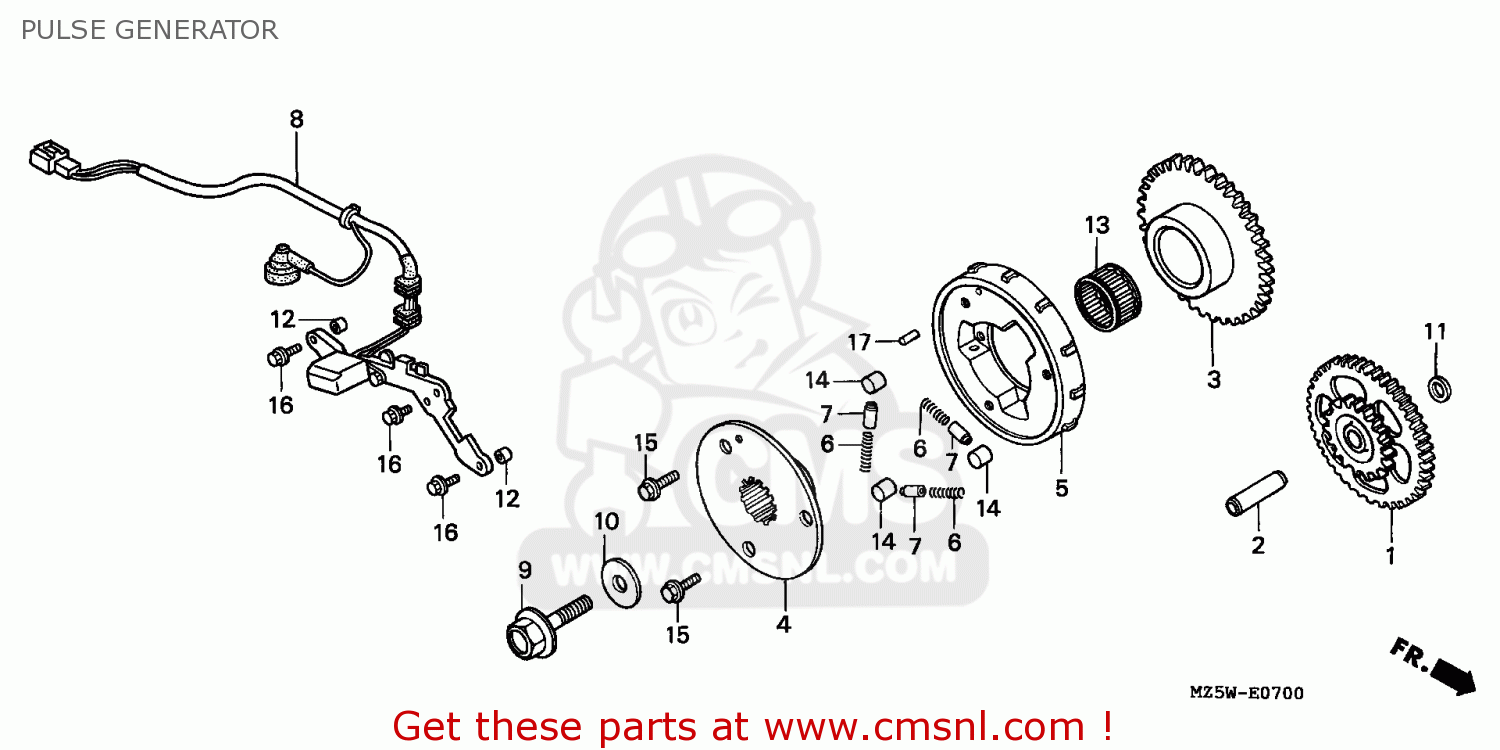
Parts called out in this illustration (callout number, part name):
1	GEAR,STARTER REDU
2	PIN,10X36.5
3	GEAR COMP.,START.
4	FLANGE,START CLUT
5	OUTER COMP,START
6	SPRING,STARTING C
7	CAP,START.ROLLER
8	PULSE GEN ASSY
9	BOLT,FLG.,12X45
10	WASHER,12X30X4.5
11	WASHER,18X10
12	PIN, DOWEL, 8X8
13	BRG,NDL.30X35X17
14	ROLLER,
15	BOLT,FLANGE,8X14
16	BOLT,FLANGE,SH,6X25
17	ROLLER,6X15
